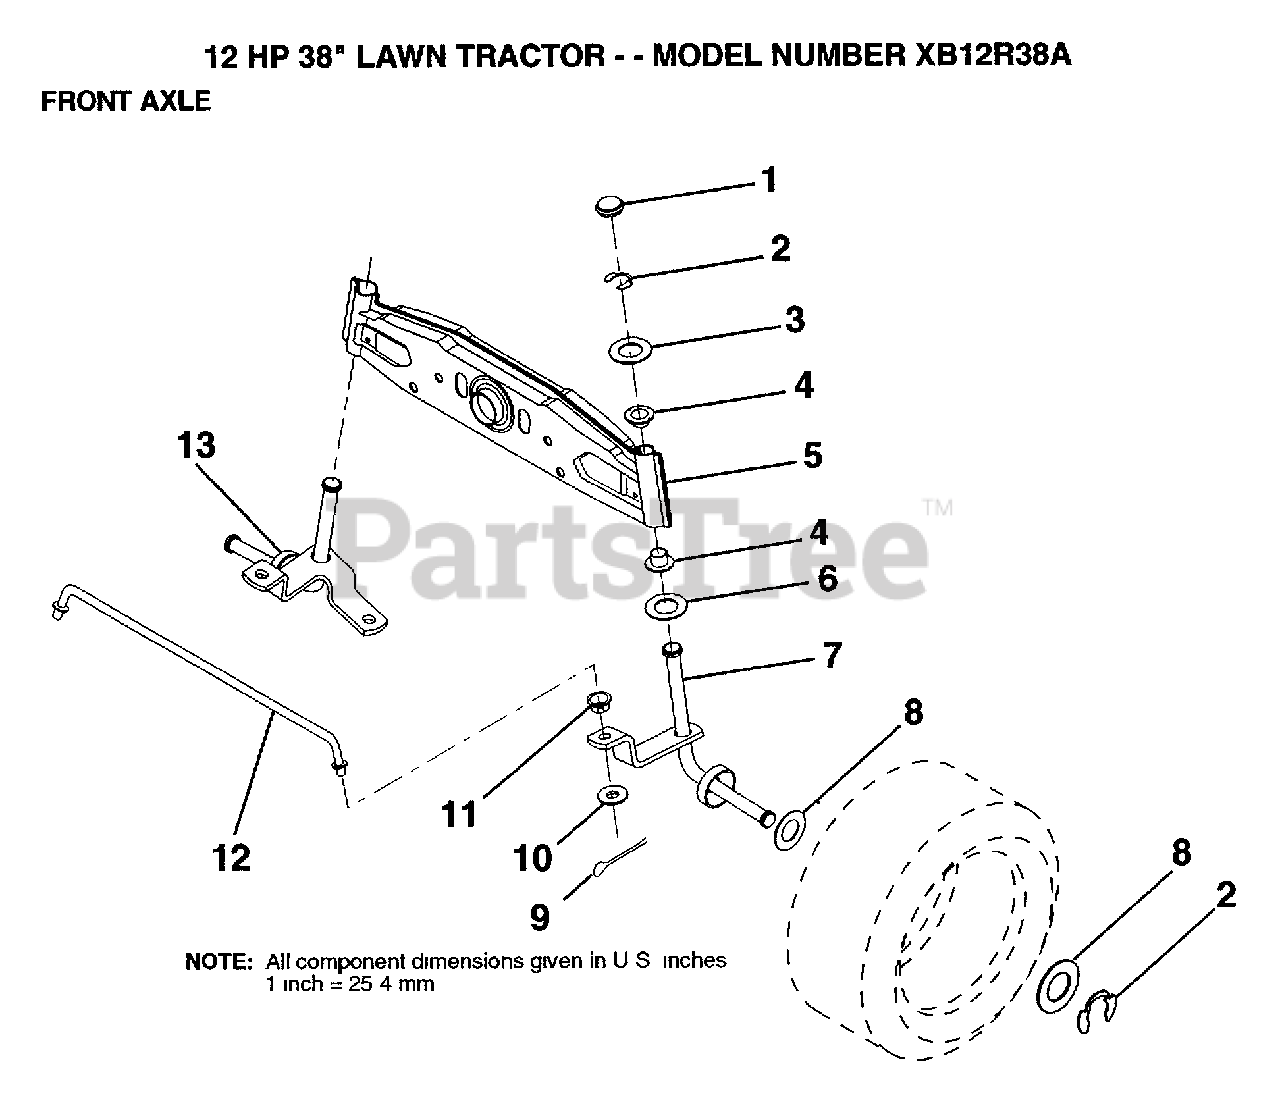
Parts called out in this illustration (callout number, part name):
1	CAP
2	RING
3	WASHER
4	NYLINER
5	AXLE FRONT
6	WASHER .T
7	SPINDLE RH
8	WASHER
9	COTTER PIN
10	WASHER
11	BUSHING.DRAGLINK
12	ROD TIE
13	SPINDLE LH
